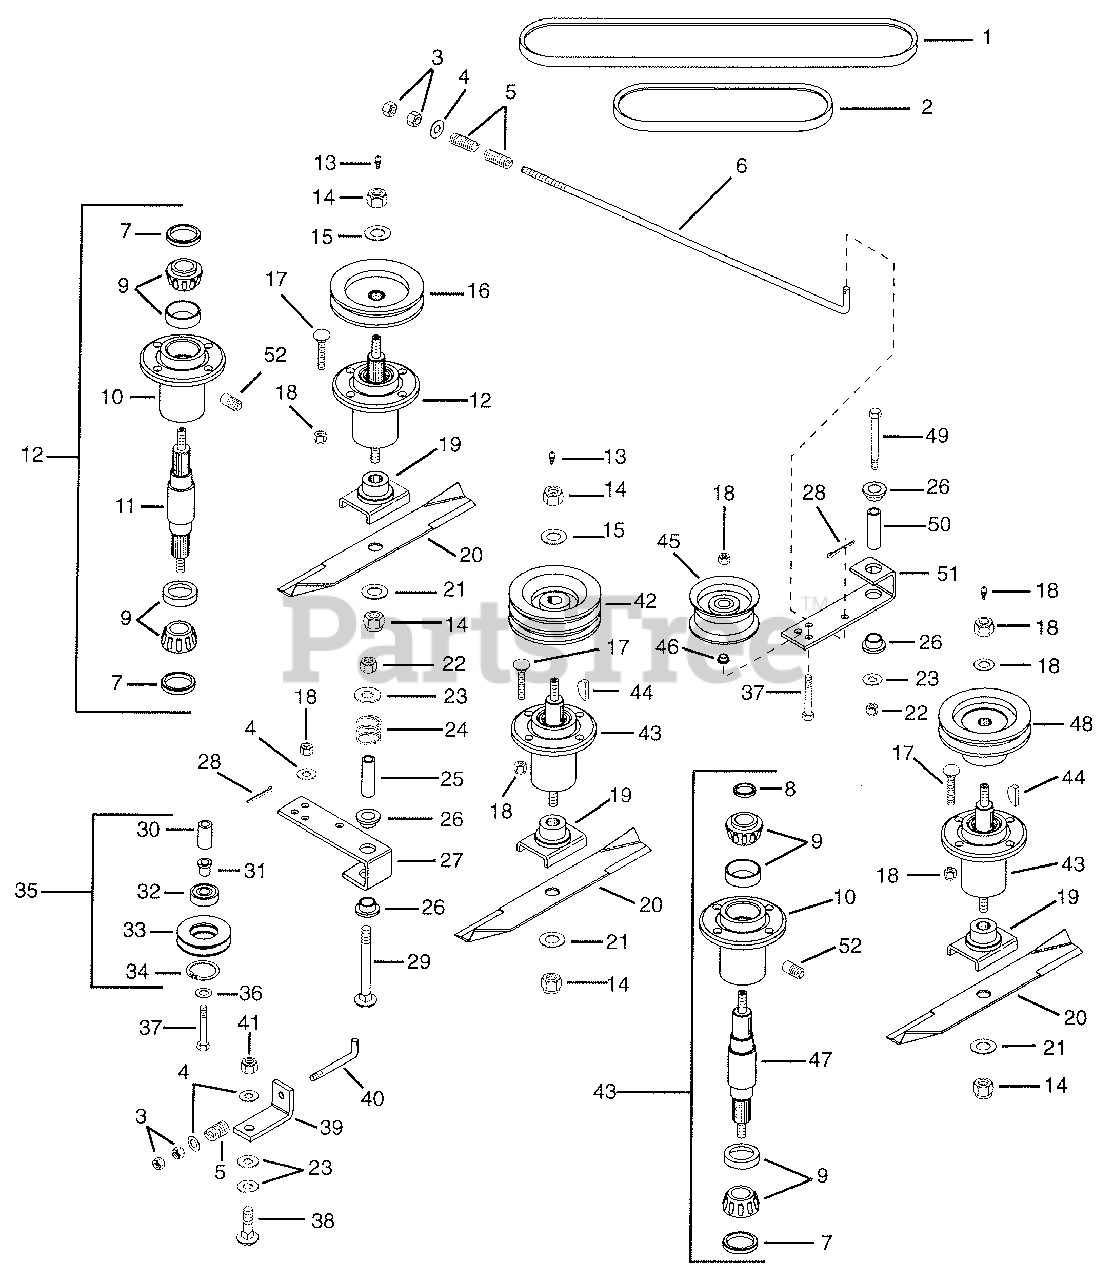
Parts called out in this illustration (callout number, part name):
1	Drive Belt 56.60 X 17/32
2	Right Spindle Belt 24.90 X .500/.031
3	Nut Hex .375-16 Grade 2
4	Washer Flat Steel .406 X .812 X .065
5	Spring Compression .125 X .78 X 1.00
6	Rod, Idler
7	Seal 1.987 X 1.375 X .313
8	Seal 1.987 X 1.500 X .313
9	Assembly, Bearing Cup & Cone
10	Bearing Housing
11	Shaft, Spindle
12	Service Kit Apindle Assembly
13	Fitting, Lube 1/8
14	Nut Locking Nylon .625-11 Grade 2
15	Washer Flat Steel .687 X 1.312 X .135
17	Bolt Round Head Square Neck .38-16 X 1.375
18	Nut Locking Nylon .375-16 Grade 2
19	Weldment Blade Cradle
20	Blade, 60 Inch Mower
21	Washer Flat Steel .656 X 1.312 X .095
22	Nut Locking .50-13
23	Washer Flat Steel .531 X 1.250 X .100
24	Spring Compression .085 X 1.00
25	Bushing Steel .560 X .750 X 2.44
26	Bushing Flange .762 X 1.0 X .580 X 1.48
27	Arm Idler Pivot
28	Pin Cotter .09 X 1.0
29	Bolt Round Head Square Neck .50-16 X 3.50
30	Bushing Steel .406 X .625 X .480
31	Bushing Flange .786 X 1.0 X .79
32	Bearing Ball 1.85 X .787 X .55
33	Sheave Idler
34	Ring Retaining Internal 2.054 X .062
35	Assembly Idler Sheave
36	Washer Flat Steel .375 X 1.125 X .065
37	Bolt Hex .38-16 X 2.25 Grade 5
38	Bolt Round Head Square Neck .38-16 X 1.25
39	Bracket Belt Tensioner
40	Rod Idler
41	Nut Locking Nylon .375-16 Grade 2
43	Service Kit Spindle Assembly
44	Key, Woodruff .25 X 1
45	Idler Flat 4-.687 X .38
46	Bushing Flange .406 X .88 X .270 X .140
47	Shaft Spindle
49	Bolt Hex .50-13 X 3.00
50	Bushing Steel .560 X .745 X 2.04
51	Weldment Idler Arm
52	Relief Fitting
